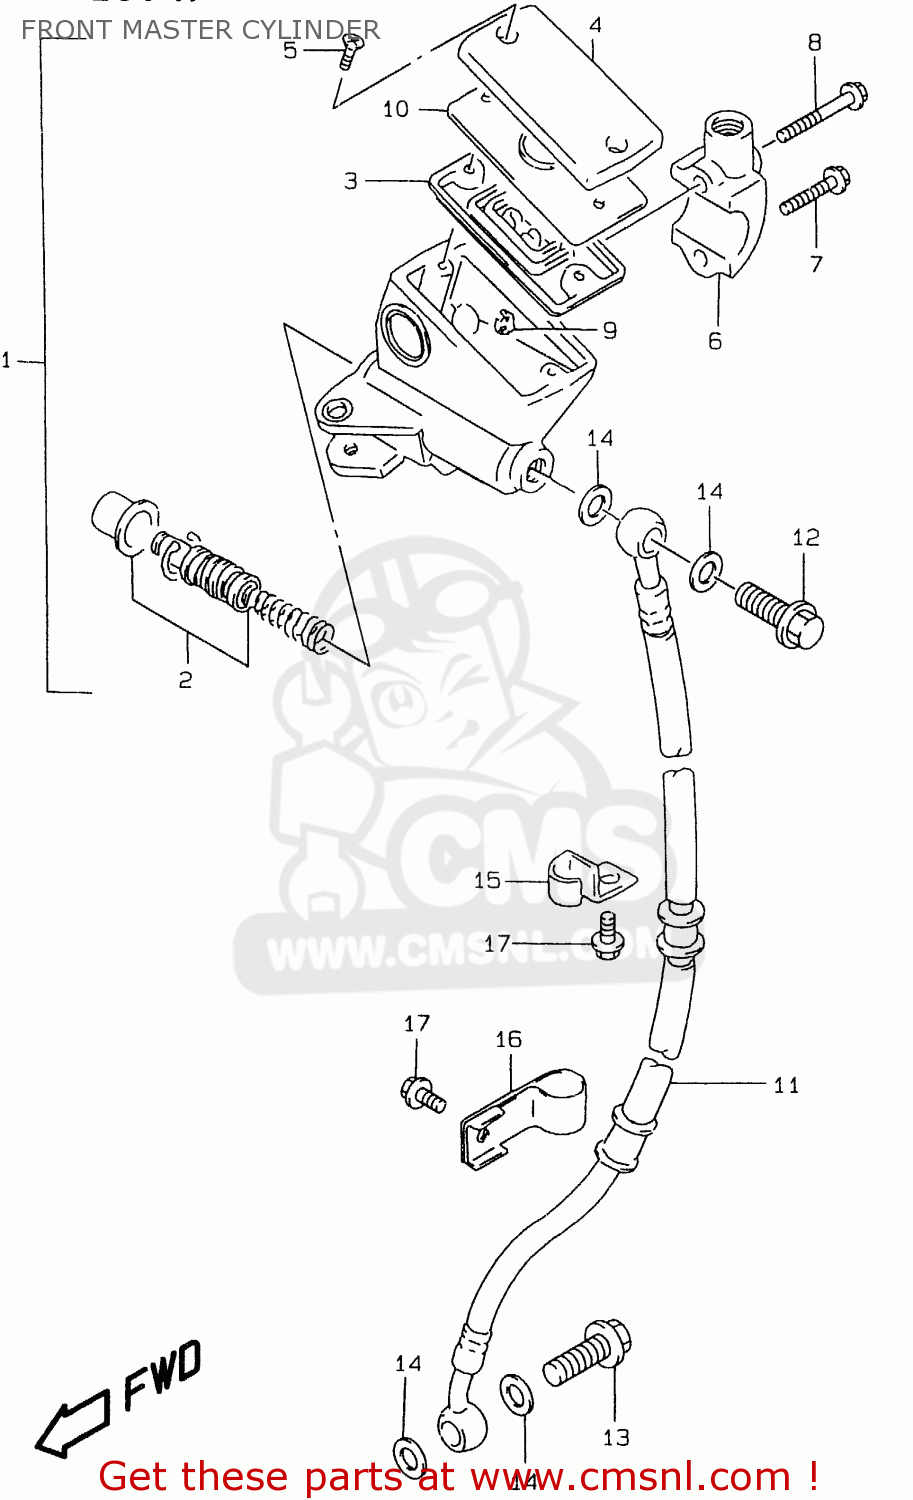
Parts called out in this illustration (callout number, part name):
1	CYLINDER ASSY,FR MASTER
2	PISTON/CUP SET
3	4
4	CAP
5	SCREW
6	HOLDER
7	BOLT(6X25)
8	BOLT(6X38)
9	PROTECTOR
10	PLATE,DIAPHRAGM
11	HOSE,FR BRAKE,R
12	BOLT UNION
13	BOLT UNION
14	WASHER(10X15X1.5)
15	CLAMP,FR BRAKE HOSE
16	CLAMP,FRONT BRAKE NO.2
17	BOLT
